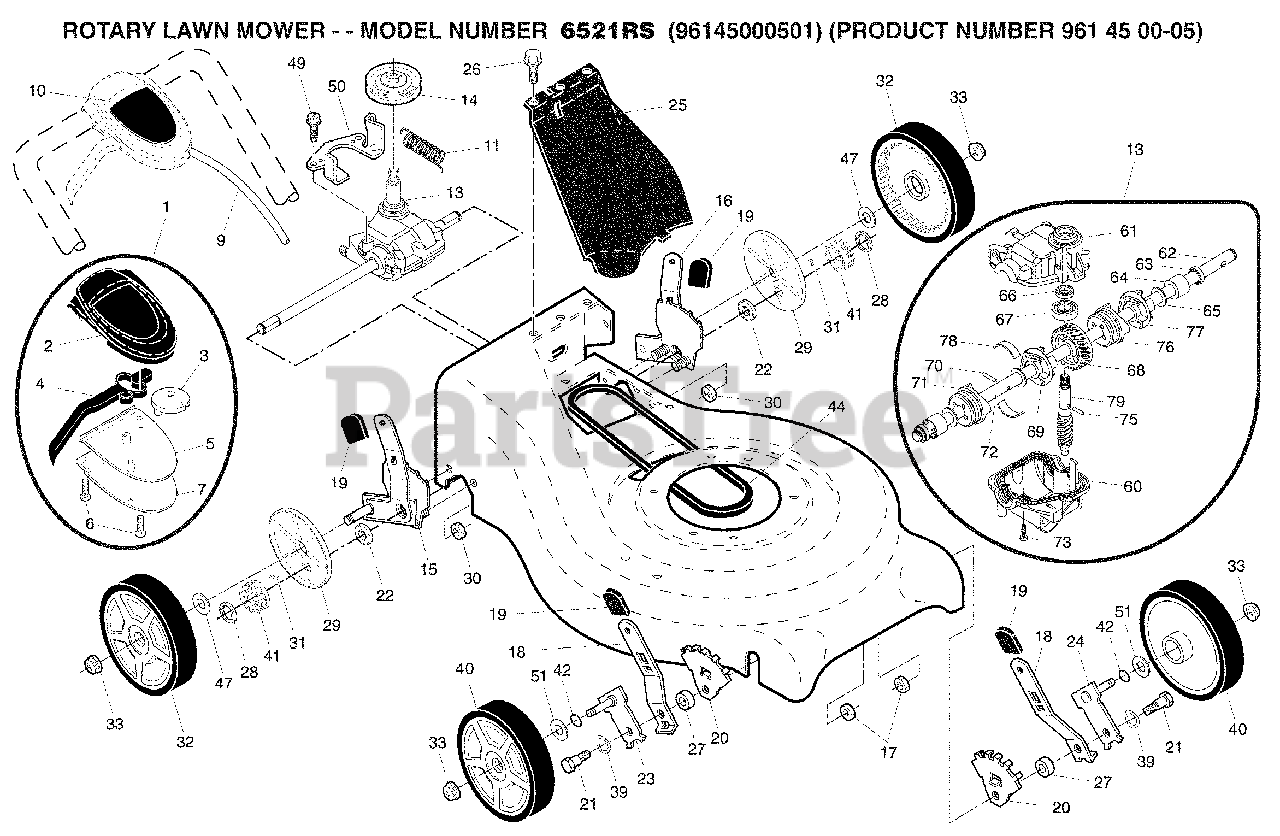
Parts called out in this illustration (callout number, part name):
1	Drive Control Assembly
2	Cover, Top, Drive Control
4	Lever, Drive Control
5	Cover, Bottom, Drive Control
6	Screw, Phillips Head #10 x 5/8
7	Mounting Bracket, Drive Control
9	Cable, Drive Control
10	Decal, Drive Control
13	Gear Case Assembly, Complete
14	Pulley, Drive
15	Kit, Wheel Adjuster Assembly, RH
16	Kit, Wheel Adjuster Assembly, LH
17	Nut, Hex
18	Spring Selector
19	Knob, Selector Spring
20	Bracket, Wheel Adjusting
21	Bolt, Shoulder, Hex Head
22	Bearing, Ball
23	Axle Arm Assembly, RH
24	Axle Arm Assembly, LH
25	Cover Drive
26	Screw, Threaded, Rolled #10-25 x 1/2
28	E-Ring 7/16
29	Cover, Dust, Wheel
30	Nut, Hex
32	Wheel & Tire Assembly, Rear
33	Nut, Hex, Flangelock 3/8-16
39	Washer, Curved, Cylindrical
40	Wheel & Tire Assembly, Front 8
41	Gear, Pinion
47	Washer 1/2 x 1-1/2 x .134
49	Screw, Hi-Lo Thread #12 x 5/8
50	Belt Keeper
51	Washer, Flat 1/2
60	Case, Lower
61	Case, Upper
62	Shaft, Output, Long
63	Seal, Output Shaft
66	Seal, Worm Shaft
67	Bearing, Ball
68	Gear, 28 Teeth
69	Fixed Dog Clutch, LH
70	Pin, Output Shaft
71	Movable Dog Clutch, LH
72	Shaft, Output, Short
73	Screw, Case
75	Pin, Worm Shaft
76	Fixed Dog Clutch, RH
77	Movable Dog Clutch, RH
78	Spring, Leaf
79	Shaft, Worm
